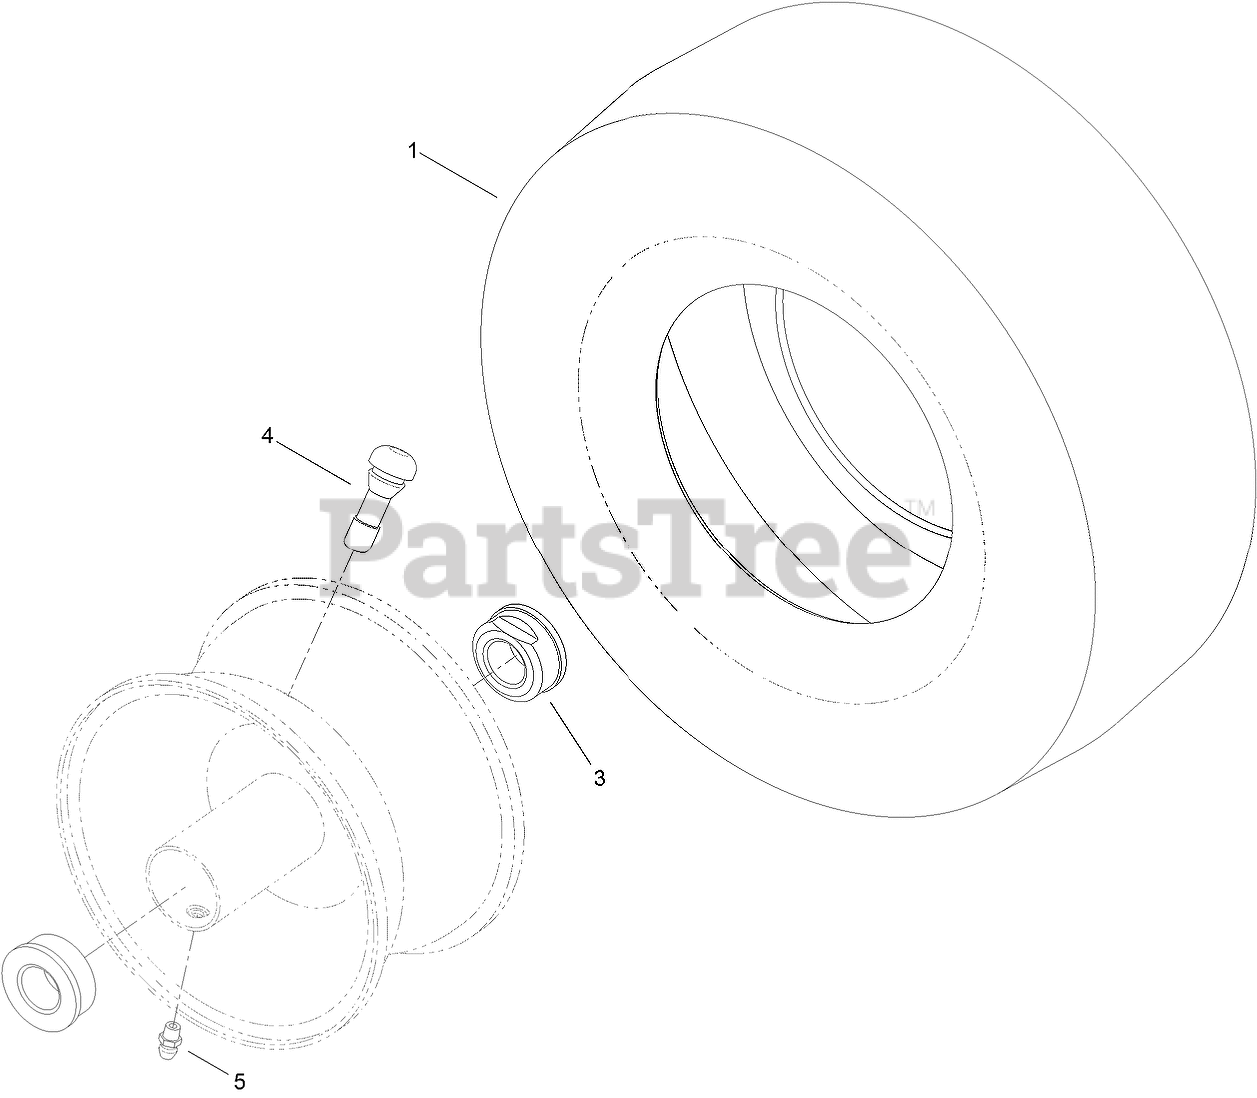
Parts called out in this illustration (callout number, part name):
1	TIRE-13 Inch
3	BUSHING-FLANGE
4	STEM-VALVE
5	FITTING-GREASE
